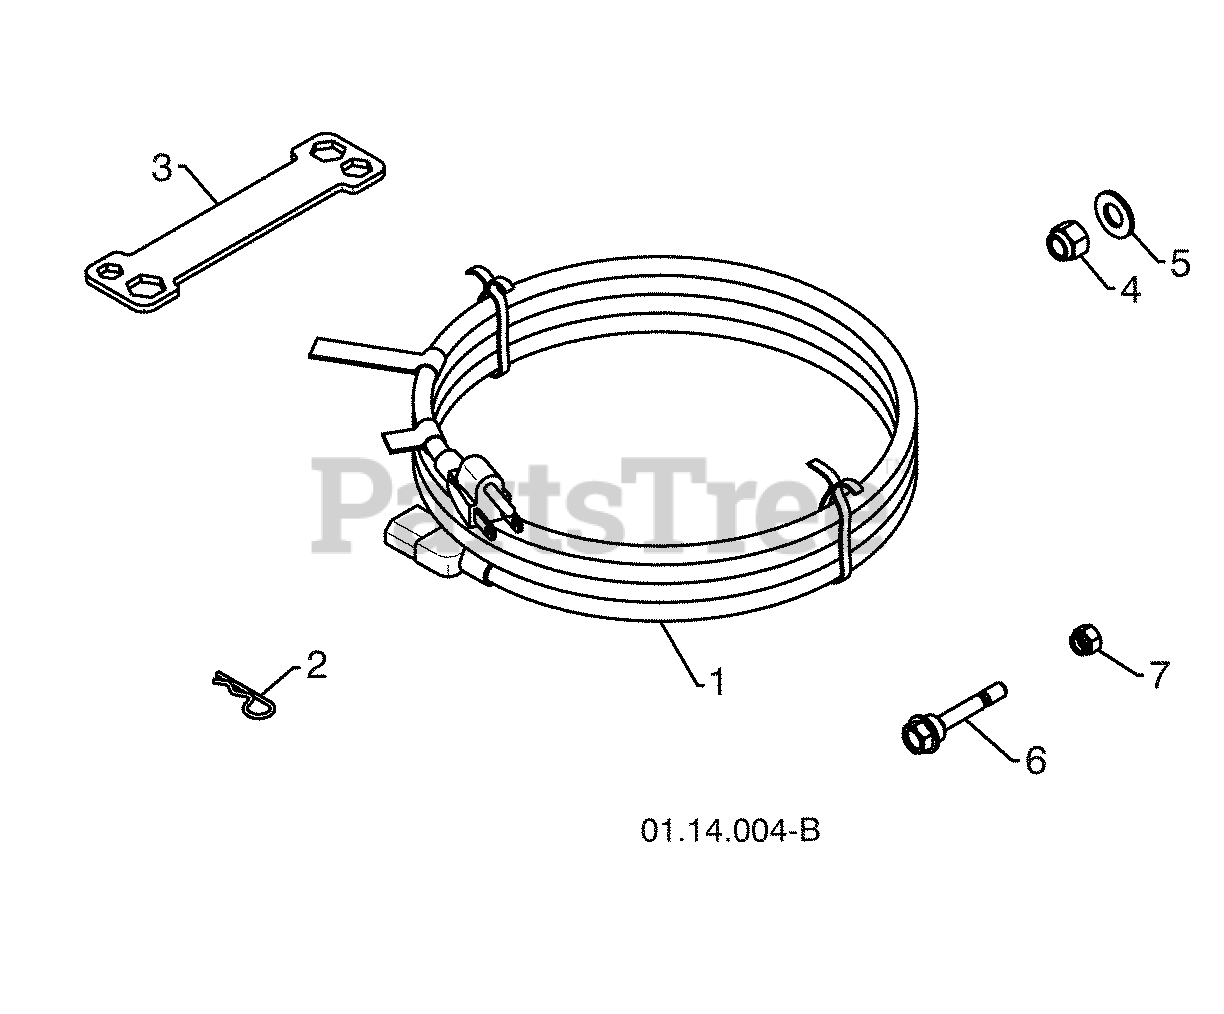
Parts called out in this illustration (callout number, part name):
1	POWER CORD
2	RETAINER PIN
4	LOCKNUT 3/8-16
5	WASHER 3/8
6	SHEAR BOLT 1/4-20 X 1-3/4
7	LOCKNUT 1/4-20
